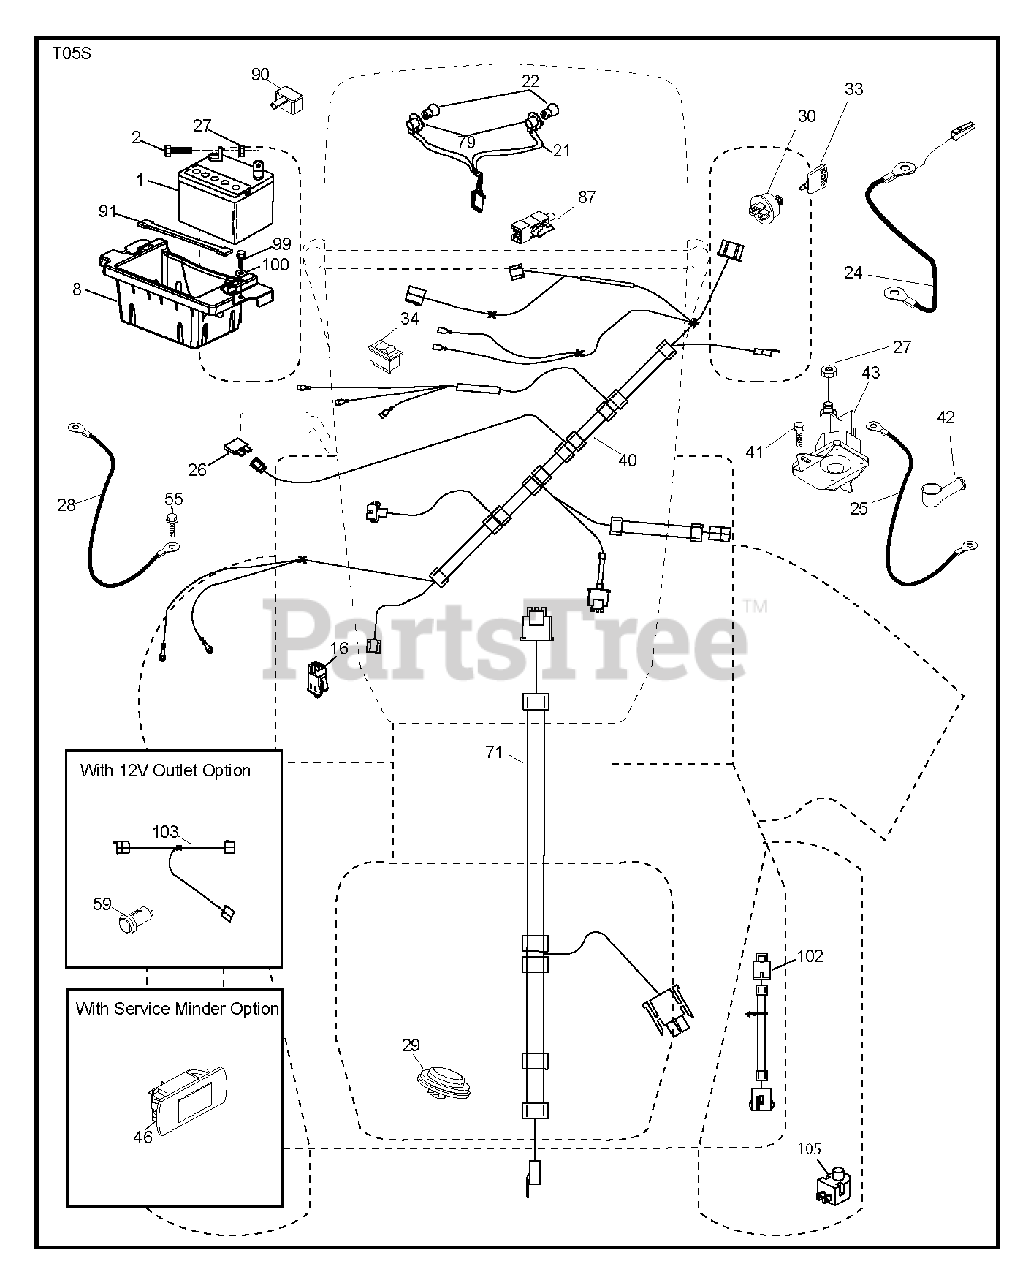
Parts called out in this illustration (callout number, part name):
1	REPL BY 532 12 38-99
2	BOLT.HEX.1/4.X.3/4.DICHROMATE
8	TRAY.BATTERY.FRONT.CARB
16	SWITCH INTERLOOK PUSH-IN
21	HARNESS.LIGHT W/4152J BULBS
22	LIGHTBULB
24	CABLE.BATT.POS.WIRE.TG.DA SOL
25	CABLE.STARTER.6G.BL/RED.17.5
26	FUSE 20AMP
27	NUT
28	CABLE GROUND 6 GA 21" 90T BLK
29	SWITCH.SEAT.DELTA.OPC.
30	SWITCH.IGN.DELTA.W.LGH.ROS
33	KEY.CHAIN.BLISTER.PACK.GEN.USA
34	SWITCH LT
40	HARNESS IGN. DASH
41	SCREW
42	TERMINAL COVER
43	SOLENOID.W/BRASS.PLUNGER
55	SCREW 5/16"
71	HARNESS-CHASSIS SUB
79	BULB HOLDER ASM.
87	SWITCH.INTRLCK.CLUTCH.
90	COVER.TERMINAL.BATTERY
91	STRAP.BATTERY.MOUNT.FRONT
99	SCREW HEXWSHR 1/4-20X3/4
102	HARNESS.PIGTAIL.VARIATOR.SD
105	REVERSE SWITCH
